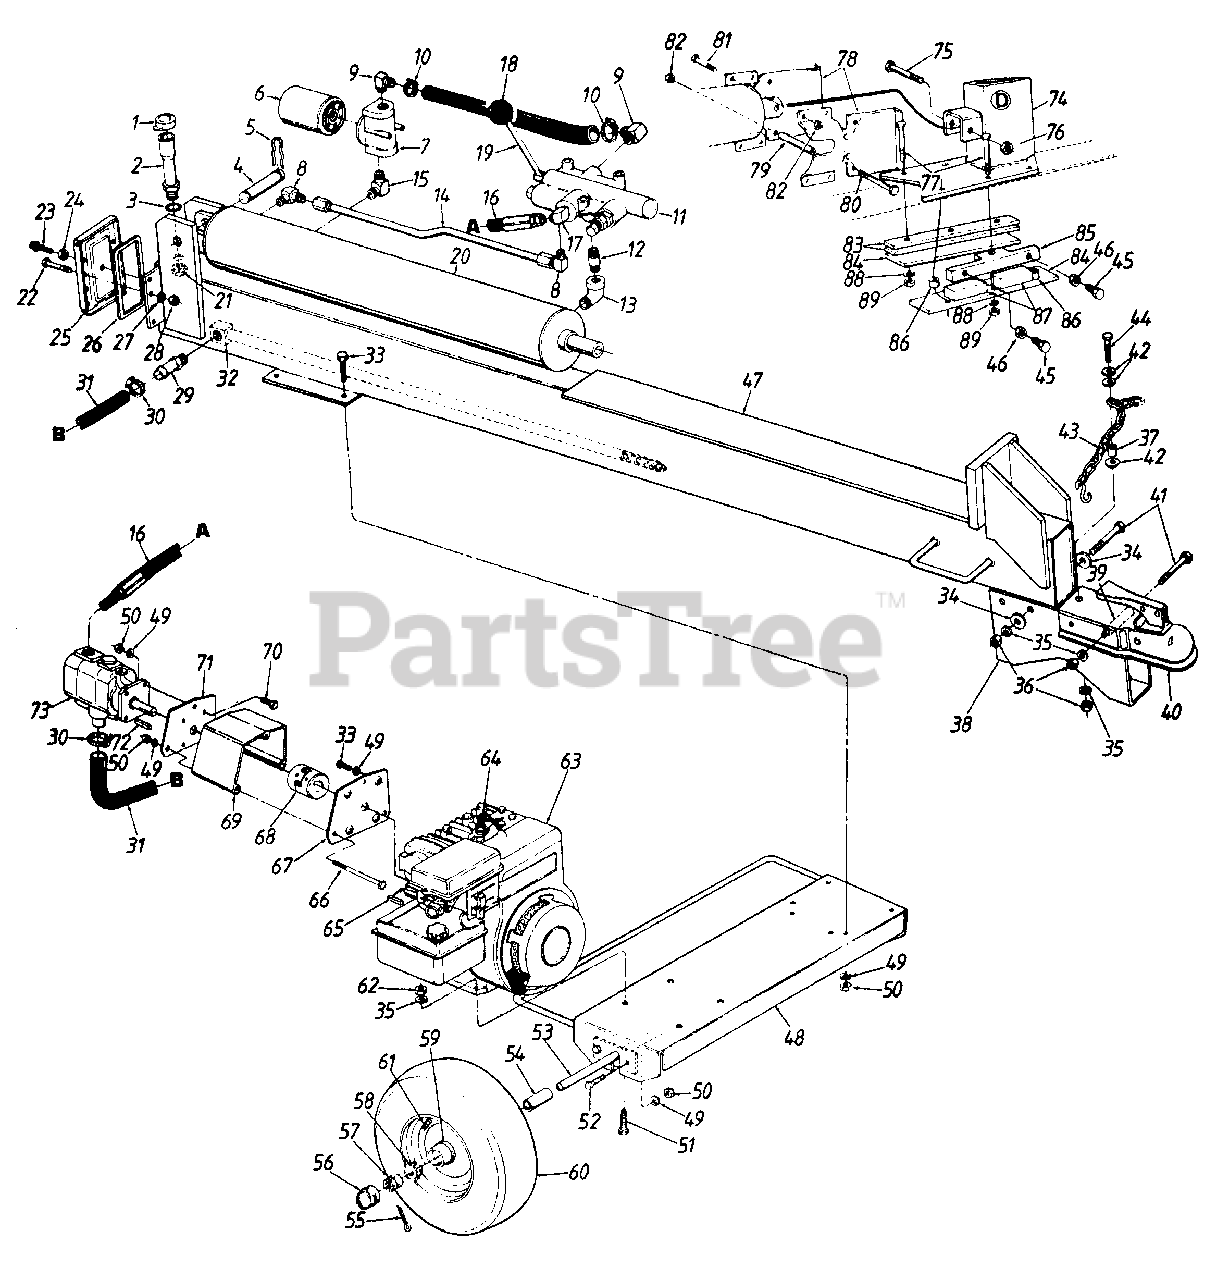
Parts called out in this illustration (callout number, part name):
1	Cap Ass'y.
2	Filler Tube Ass'y.
3	"O" Ring .92" I.D.
4	Cylinder Mtg. Pin 3.82" Lg.
5	External Cotter Pin
6	Filter Element
7	Filter Head
8	9Oø Solid Male Adapter
9	Return Elbow
10	Adj. Hose Clamp
11	Control Valve
12	Pipe Nipple 1/2 NPT x 2" Lg.
13	Street Elbow 1/2" Male x 1/2" Female NPT
14	Metal Pressure Tube
15	Male Pipe Elbow 3/4"
16	High Pressure Hydraulic Hose 27.5" Lg
17	90ø Solid Male Adapter
18	Ball Knob
19	Control Handle
20	Hydraulic Cylinder
21	Hex Nut 1-1/16-12 Thd.
22	Hex Bolt 5/16-18 x 1.5" Lg.
23	Hex Wash. TT-Tap Scr. 5/16-18 x.62" Lg.
24	Gasket Washer 5/16" I.D.
25	End Plate
26	Gasket
27	Fl-Wash. .34" I.D. x .68" O.D.
28	Hex L-Nut 5/16-18 Thd.
29	Adapter 1" x 1-1/16-12 Thd.
30	Hose Clamp 518"
31	Suction Hose 1.0" I.D.
32	Strainer Tube Ass'y.
33	Hex Bolt 5/16-24 x 1.0" Lg.
34	Shld. Spacer.625" I.D.
35	L-Wash. 3/8" I.D.
36	Hex Nut 3/8-16 Thd. (Grade 5)
37	Spacer .38" I.D. x .625" O.D.
38	Beam Stand
39	Spacer .375" I.D. x .625" O.D.
40	Hitch Ass'y.
41	Hex Bolt 3/8-16 x 3.25" Lg. (Grade 8)
42	Fl-Wash. .375" I.D. x .87" O.D.
43	Chain-Tow Hitch
44	Hex Bolt 3/8-16 x 1.5" Lg. (Grade 5)
45	Hex Bolt 3/8-24 x 1.5" Lg.
46	Hex Jam Nut 3/8-24 Thd.
47	Tank & Beam Ass'y.
48	Engine Frame Ass'y.
49	L-Wash. 5/16" I.D.
50	Hex Nut 5/16-24 Thd.
51	Hex Bolt 3/8-24 x 1.0" Lg.
52	Hex Bolt 5/16-24 x 1.75" Lg.
53	Axle Ass'y.
54	Spacer .75" I.D. x 1.56" Lg.
55	Cotter Pin 5/32" Dia.
56	Hub Cap
57	Hex Slotted Nut 3/4-16 Thd.
58	Roller Bearing w/Race
59	Bearing Seal
61	Air Valve
62	Hex Nut 3/8-24 Thd.
64	Spark Plug Boot
65	Sq. Key 3/16-.75" Lg.
66	Hex Bolt 5/16-24 x 4" Lg.
68	Flexible Coupling
69	Coupling Shield
70	Hex Bolt 5/16-24 x .62" Lg.
72	Hi-Pro Key 1/8" x 1/2" Lg.
73	Two Volume Pump
74	Wedge Mtg. Ass'y.
75	Hex Bolt 1/2-20 x 3" Lg. (Grade 8)
76	Hex L-Nut 1/2-20 Thd.
77	Hex Bolt 1/2-20 x 2.75" Lg. (Grade 8)
80	Hex Bolt 3/8-16 x 5.5" Lg
81	Hex Bolt 3/8-16 x 2" Lg. (Grade 5)
82	Hex L-Nut 3/8-16 Thd.
83	Fixed Side Gib
84	Pusher Back Plate
86	Spacer 1/2" I.D. x .68" Lg.
88	L-Wash. 1/2" I.D.
89	Hex Nut 1/2-20 Thd.
